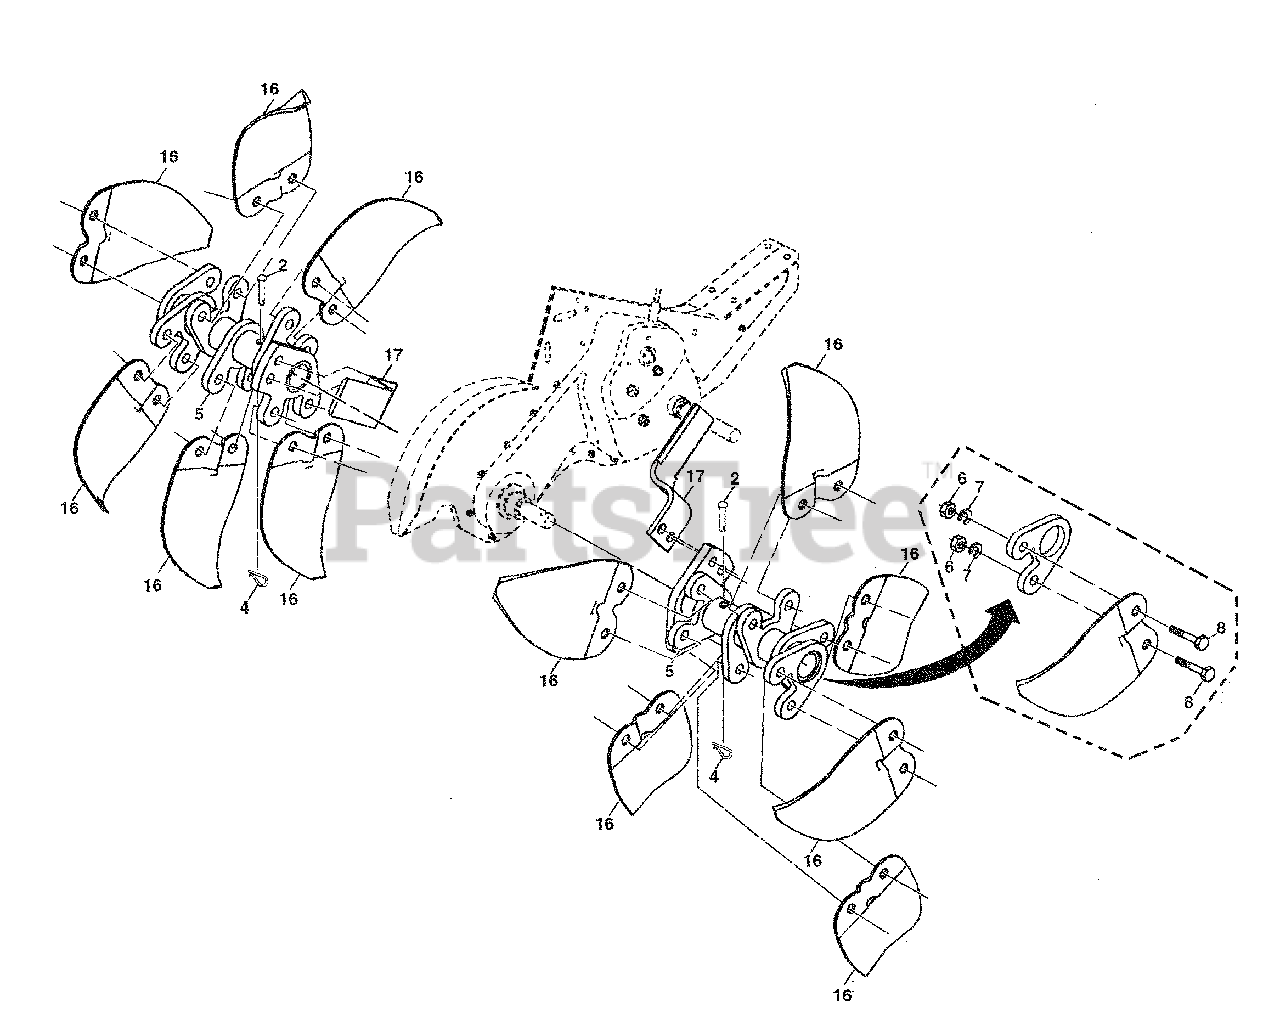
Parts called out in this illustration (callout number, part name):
1	Pin, Shear
2	Clip, Hairpin
3	Hub Assembly
4	Nut, Hex 3/8-24
5	Washer, Lock 3/8
6	Bolt, Hex 3/8-24 x 1
7	Tine, Spade
8	Tine, Cleaning
